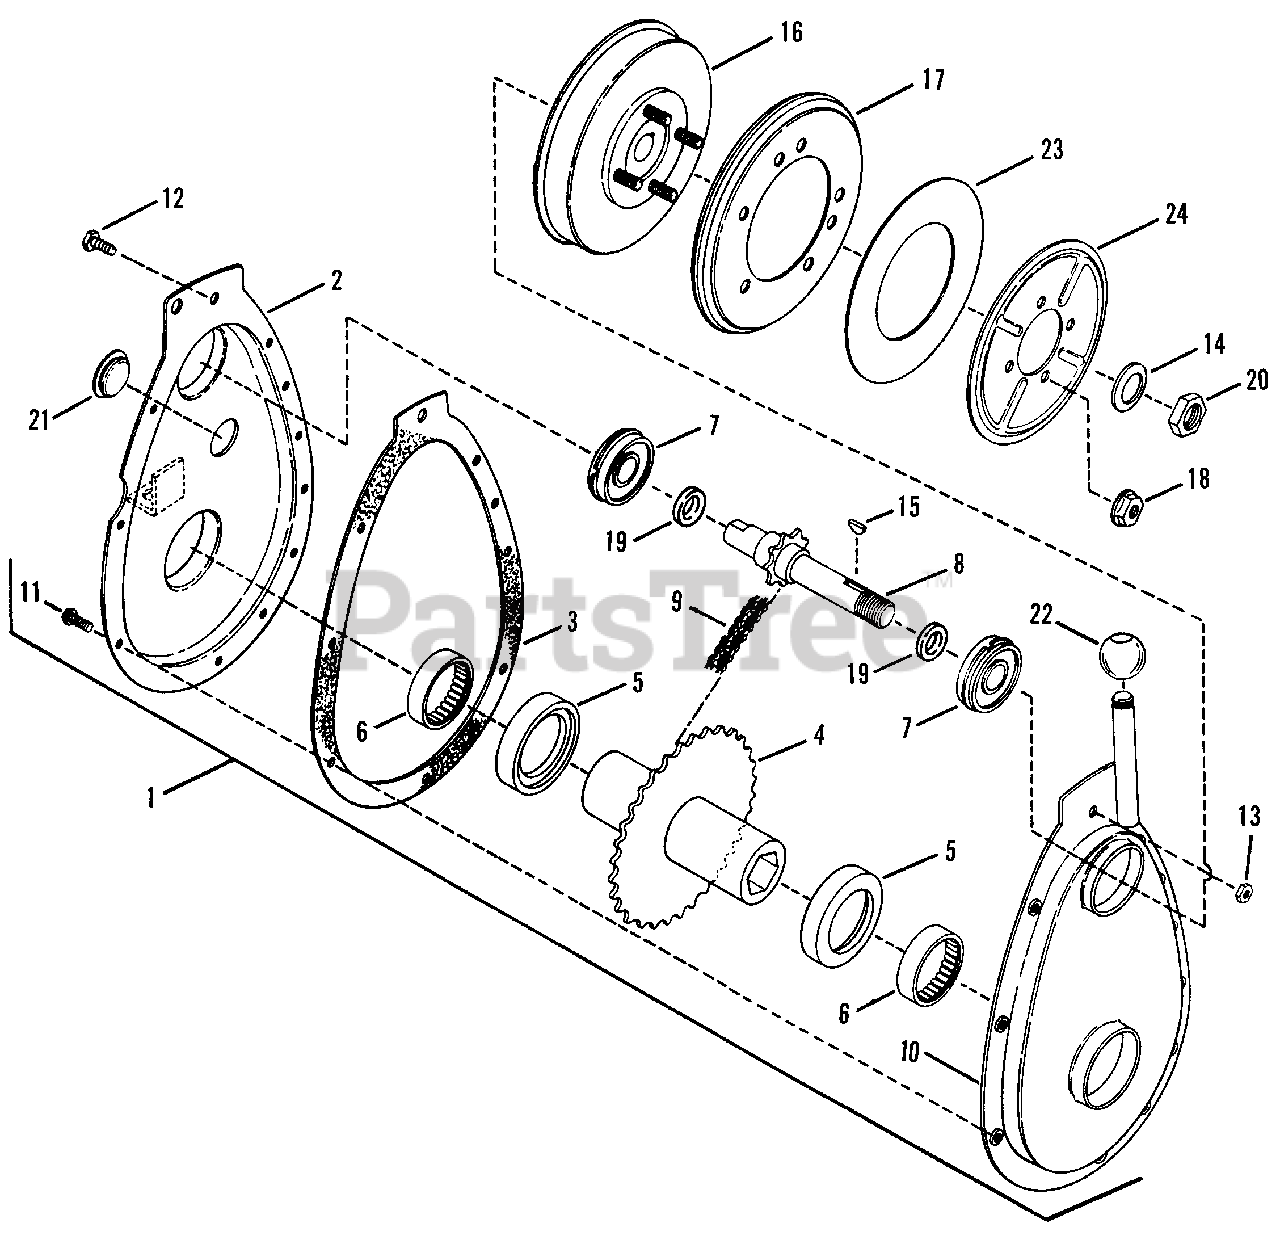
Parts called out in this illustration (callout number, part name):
1	ASSEMBLY, Primary Chain Case
2	COVER, Case
3	GASKET, Case/Cover
4	HUB & SPROCKET
5	THRUST-WASHER
6	BEARING, Needle
7	BEARING, Ball
8	SHAFT, Input
9	CHAIN, 46 Pitch (#35)
10	CASE, Sprocket
11	SCREW, #10-24 x 1/2" Hex Washer Self-Tap (Torx)
12	SCREW, 1/4-20 x 5/8" Hex Head Cap, Gr. 5
13	NUT, 1/4-20 Hex Center Lock
14	WASHER, Belleville
15	KEY, 1/8 x 5/8 Woodruff
16	HUB, Driven Disc
17	DISC, Driven
18	NUT, 5/8-18 Hex Center Lock
19	O-RING, 5/8"
20	NUT, 5/8-18 Hex Flange Lock, Grade 5
21	PLUG (Oil fill & check)
22	BUSHING, Primary Clutch Ball
23	WASHER, Thrust
24	PLATE
